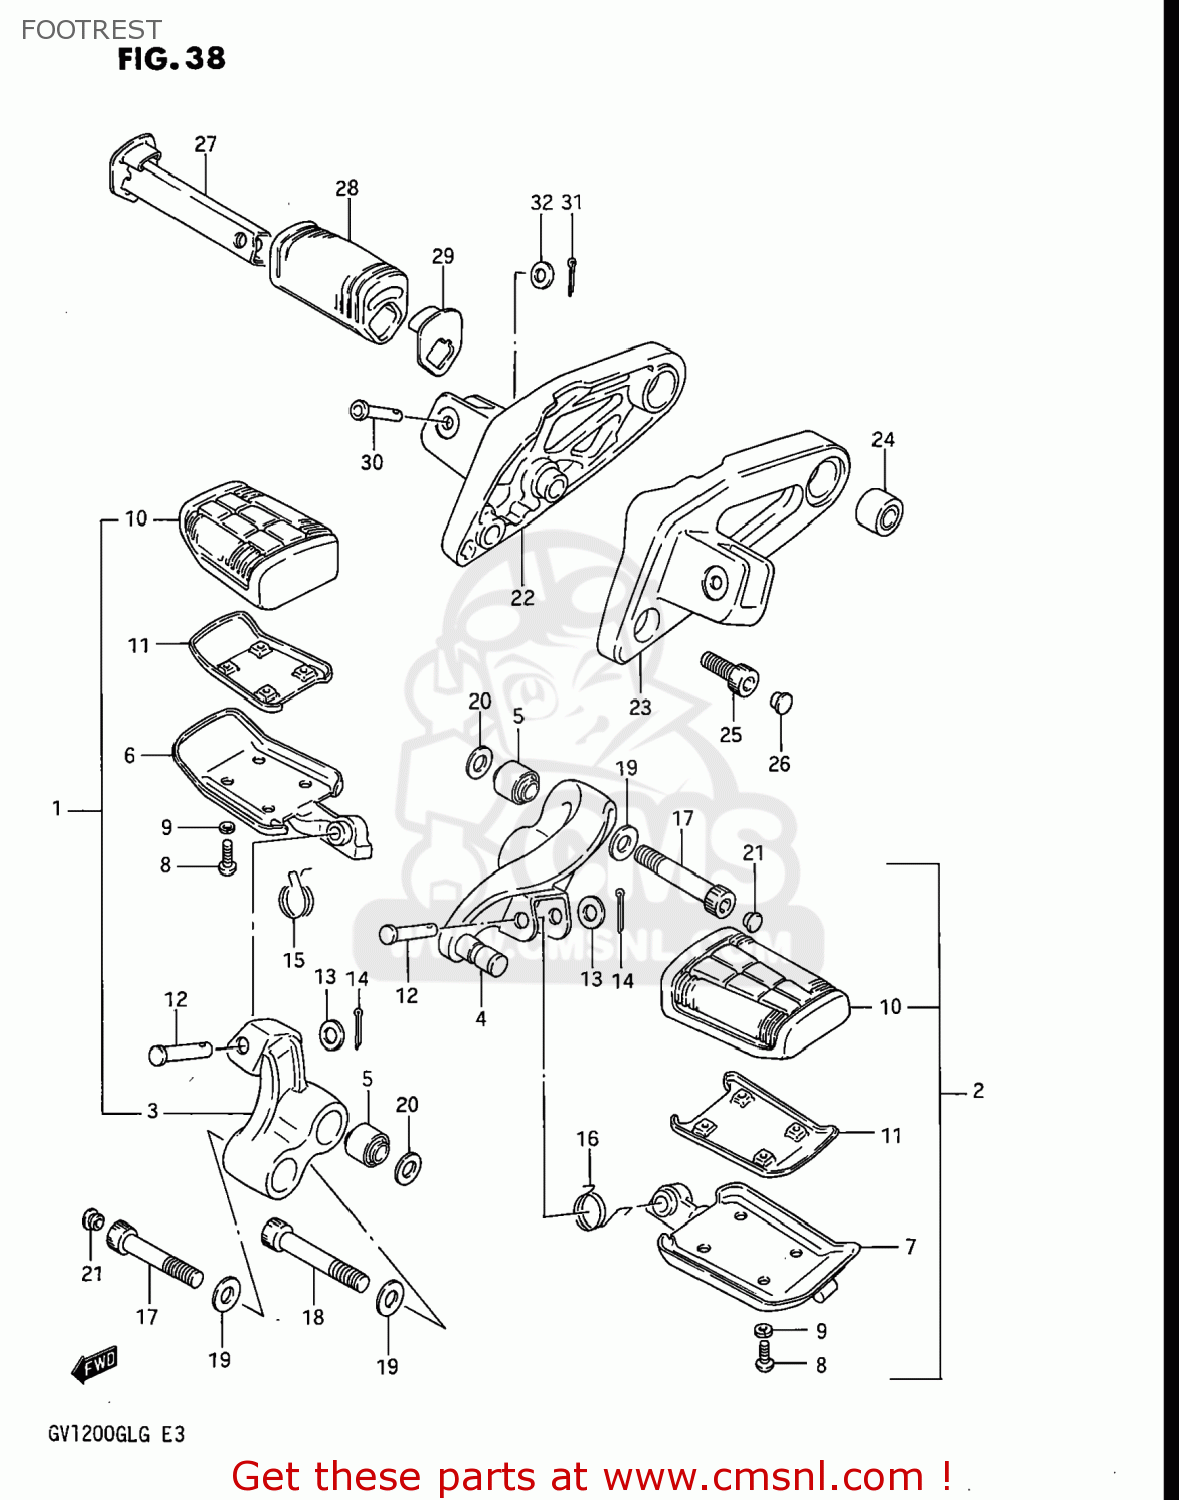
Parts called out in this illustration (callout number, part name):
1	FOOTREST ASSEMBLY,FRONT,RIGHT
2	FOOTREST ASSEMBLY,FRONT,LEFT
3	BAR,FRONT FOOTREST,RIGHT
4	BAR,FRONT FOOTREST,LEFT
5	BUSH
6	HOLDER,FRONT FOOTREST,RIGHT
8	SCREW
9	LOCK WASHER
10	RUBBER,FR FOOTREST
12	PIN
13	WASHER
14	PIN 20X20
15	SPRING
16	SPRING
17	BOLT
18	BOLT
19	WASHER
20	WASHER
21	CAP
22	BRACKET,MUFFLER,RIGHT
23	BRACKET,MUFFLER,LEFT
24	BUSH(10.2X25X19)
25	BOLT 10X25
26	CAP
27	BAR,REAR FOOTREST,LEFT
28	RUBBER,REAR FOOTREST
29	WASHER,REAR FOOTREST RUBBER
30	PIN
31	PIN 20X20
32	WASHER
